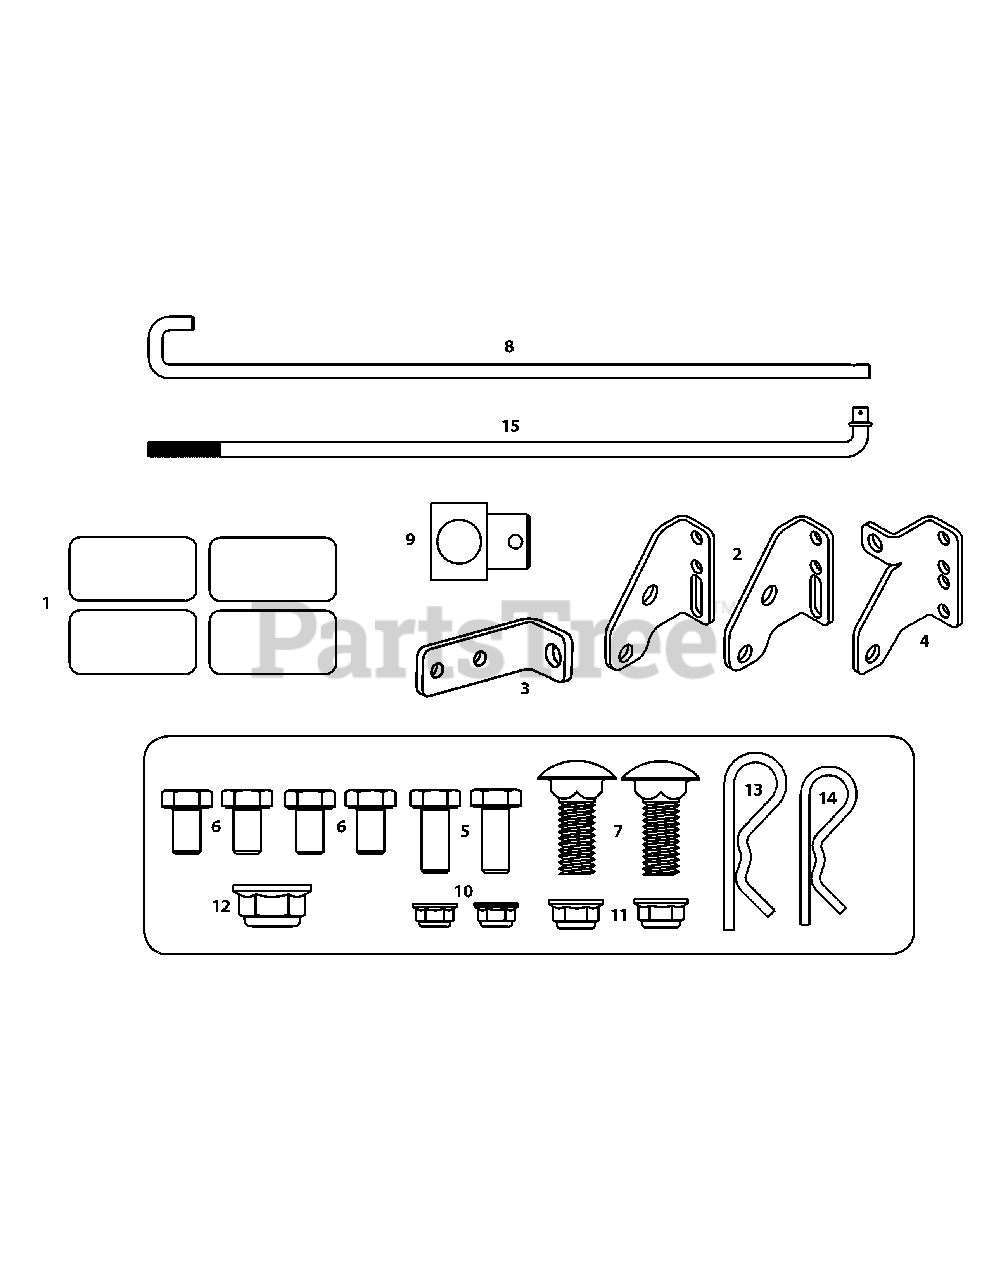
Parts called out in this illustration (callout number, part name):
1	Anti-Scalp Roller Assembly
2	Rear Roller Mount Bracket
3	Deck Stabilizer Mount Bracket
4	RH Rear Roller Mount Bracket
5	Hex Washer Screw, 3/8-16 x .750
6	Hex Washer Screw, 3/8-16 x .500
7	Carriage Bolt, 3/8-16 x 1.00
8	Roller Pin, 1/2 x 25.75
9	Adjustable Ferule
10	Jam Lock Nut, 3/8-16
11	Flange Lock Nut, 3/8-16
12	Flange Lock Nut, 1/2-13
13	Click Pin, .092 x 1.64
14	Cotter Pin, .080 x 1.5625
15	Deck Support Rod, 1/2
